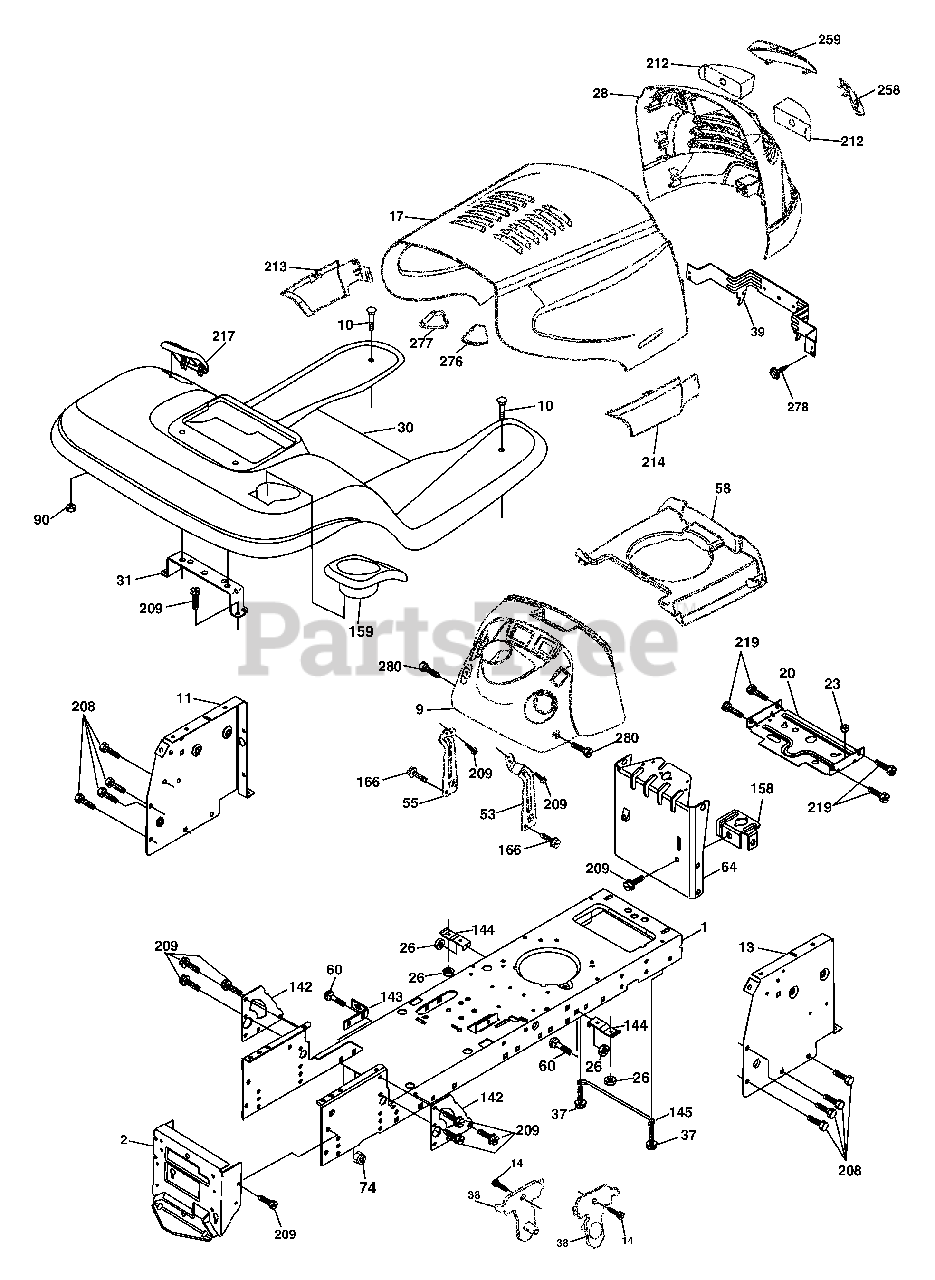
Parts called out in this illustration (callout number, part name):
1	Chassis Stamping
9	Dashboard
10	Bolt Rdhd Sqnk 3/8-16 unc x 1
11	Panel Dash Lh
13	Panel Dash Rh
14	Screw Thdrol 3/8-16 x 1/2
17	Hood
20	Plate Mtg Battery/Fuel Tank
26	Nut Lock w/Insert 3/8-16 unc
28	Grille Lens Asm
30	Fender
37	Screw Thdrol 5/16-18 x 1/2
38	Bracket Asm Pivot Mower Rear
39	Bracket Pivot
53	Bracket Dash Husq. Elite RH
55	Bracket Dash Husq. Elite LH
60	Bolt RDHD SQNK 3/8-16 x 3/4
64	Dash Lower STYT
74	Nut Crownlock 3/8-16
142	Plate Reinforcement
143	Bracket Swaybar Chassis
144	Bracket Ft Rest
145	Rod Pivot Chassis Hood
158	Bracket Parking Brake
159	Cupholder
166	Screw Hw Hd Hi-Lo #13-16 x 3/4
208	Screw Thdrol 3/8-16 x 1/2 Ty-TT
209	Screw 3/8-16 x 3/4
212	Lens Insert Reflect
213	Skirt Side Elite Husq. LH
214	Skirt Side Elite Husq. RH
217	Console Fuel Window
219	Screw 5/16-18 x 3/4
258	Lens Husq. Elite Clear RH
259	Lens Husq. Elite Clear LH
276	Bumper Hood RH
277	Bumper Hood LH
278	Screw Quadx. Wshd #10-14 x 1
280	Screw 3/8-16 x 1.0
